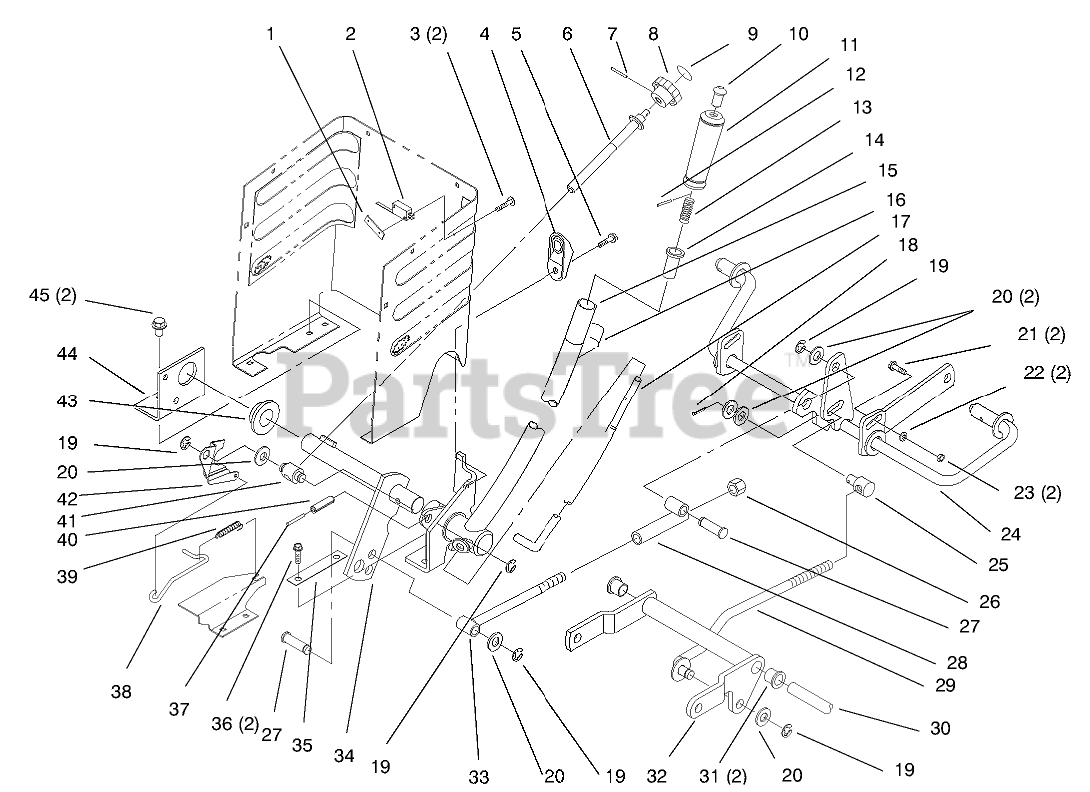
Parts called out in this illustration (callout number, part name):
1	NUT-SPEED
2	SWITCH-MICRO
3	SCREW-PPHTF
4	WEDGE - HOC
5	SCREW-HWH
6	ROD - HOC
7	PIN-SPIROL
9	DECAL-HEIGHT KNOB
10	TIP-ROD
11	GRIP-HANDLE
12	PIN-SPIROL
13	SPRING-COMPRESSION
14	RETAINER-SPRING
15	LEVER-LIFT
16	Decal-Lift (Only On: 72085)
16	Decal-Lift (Only On: 72104)
17	ROD-LEVER, LIFT
18	PIN-COTTER
19	RING-RETAINING, EXTERNAL
20	WASHER-FLAT
21	BOLT-CARR
22	WASHER-FLAT
23	NUT-LOCK, NI
24	SHAFT-GAGE
25	ROD-TRUNNION LIFT
26	NUT-LOCK, NI
30	SHAFT-PIVOT, PEDAL
31	BUSHING-FLANGE
32	ARM-PIVOT
34	SHAFT-LIFT
36	SCREW-HWHTF
37	PIN-SPRING
38	ROD - HOC INDICATOR
39	SPRING - EXTENSION
40	PIN-ROLL
41	TRUNNION
42	PLATE - HOC GAGE
43	BEARING-FLANGE
44	BRACKET-PIVOT, LINKAGE
45	SCREW-HWHTF
